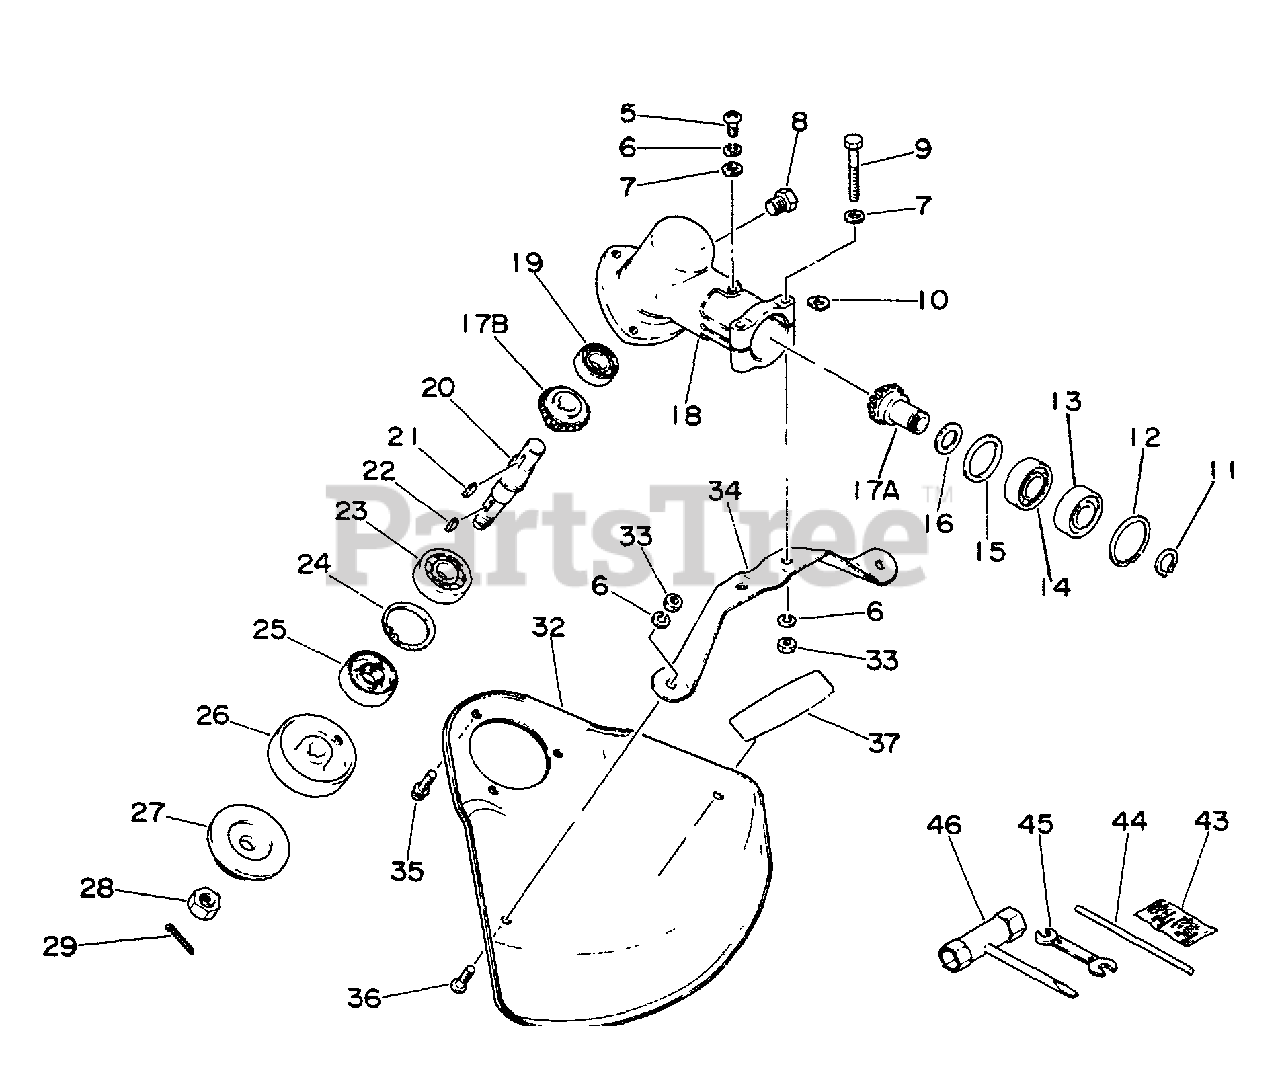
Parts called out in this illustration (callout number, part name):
5	SCREW 5×10
6	WASHER, SPRING 5
7	WASHER, FLAT 5.5×10×0.8
8	BOLT 8×8 SP
9	BOLT 5×40
11	RING, RETAINING - 12
12	RING, SNAP 28
13	BEARING, BALL 6001
14	BEARING, BALL 6001
18	CASE, GEAR
19	BEARING, BALL 6000
20	DRIVESHAFT
23	BEARING, BALL - 6201 C3
24	RING, SNAP Ø32
25	SEAL, OIL
26	PLATE, ADAPTER - UPPER
27	PLATE, ADAPTOR - LOWER
29	PIN, COTTER 2×22
32	SHIELD
33	NUT M5
34	BRACKET, SHIELD
35	SCREW 5×10
36	SCREW 5×8
37	LABEL - ECHO
43	PIN, COTTER 2×22 (PKG. OF 10)
44	TOOL, LOCKING 5×120 MM
45	SPANNER 8×10
46	T-WRENCH
